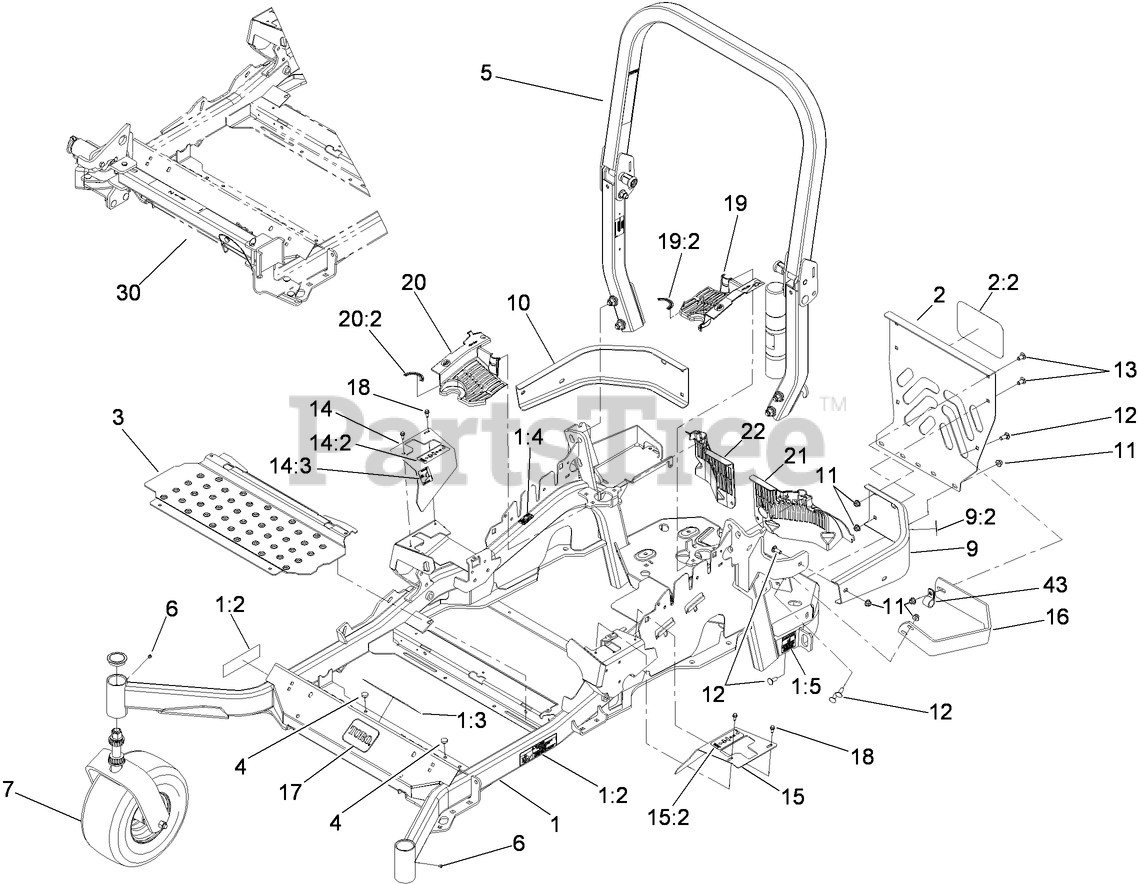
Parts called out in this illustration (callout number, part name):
1	MAIN FRAME ASM
1:2	DECAL-WARNING
1:3	DECAL-WARNING
1:4	DECAL-CAUTION
1:5	DECAL-BELT DRIVE
2	REAR GUARD ASM
2:2	DECAL
3	FLOORPAN
4	BUMPER
5	ROPS ASM
7	Caster Wheel ASM
9	LH BUMPER ASM
9:2	DECAL-CAUTION
10	BUMPER-RH
11	NUT-HF, NI
12	SCREW-CARR
13	SCREW-CARR
14	RH MOTION CONTROL COVER ASM
14:2	DECAL-MOTION CONTROL
14:3	DECAL-PARK BRAKE
15	LH MOTION CONTROL COVER ASM
15:2	DECAL-MOTION CONTROL
16	GUARD-MUFFLER
17	DECAL
18	SCREW-HWH
19	LH HYDRO GUARD ASM
19:2	DECAL-HYDRO OIL
20	RH HYDRO GUARD ASM
20:2	DECAL-HYDRO OIL
21	GUARD-HYDRO, REAR (LH)
22	GUARD-HYDRO, REAR (RH)
30	Z STAND ASM
43	CLIP-LOOM
